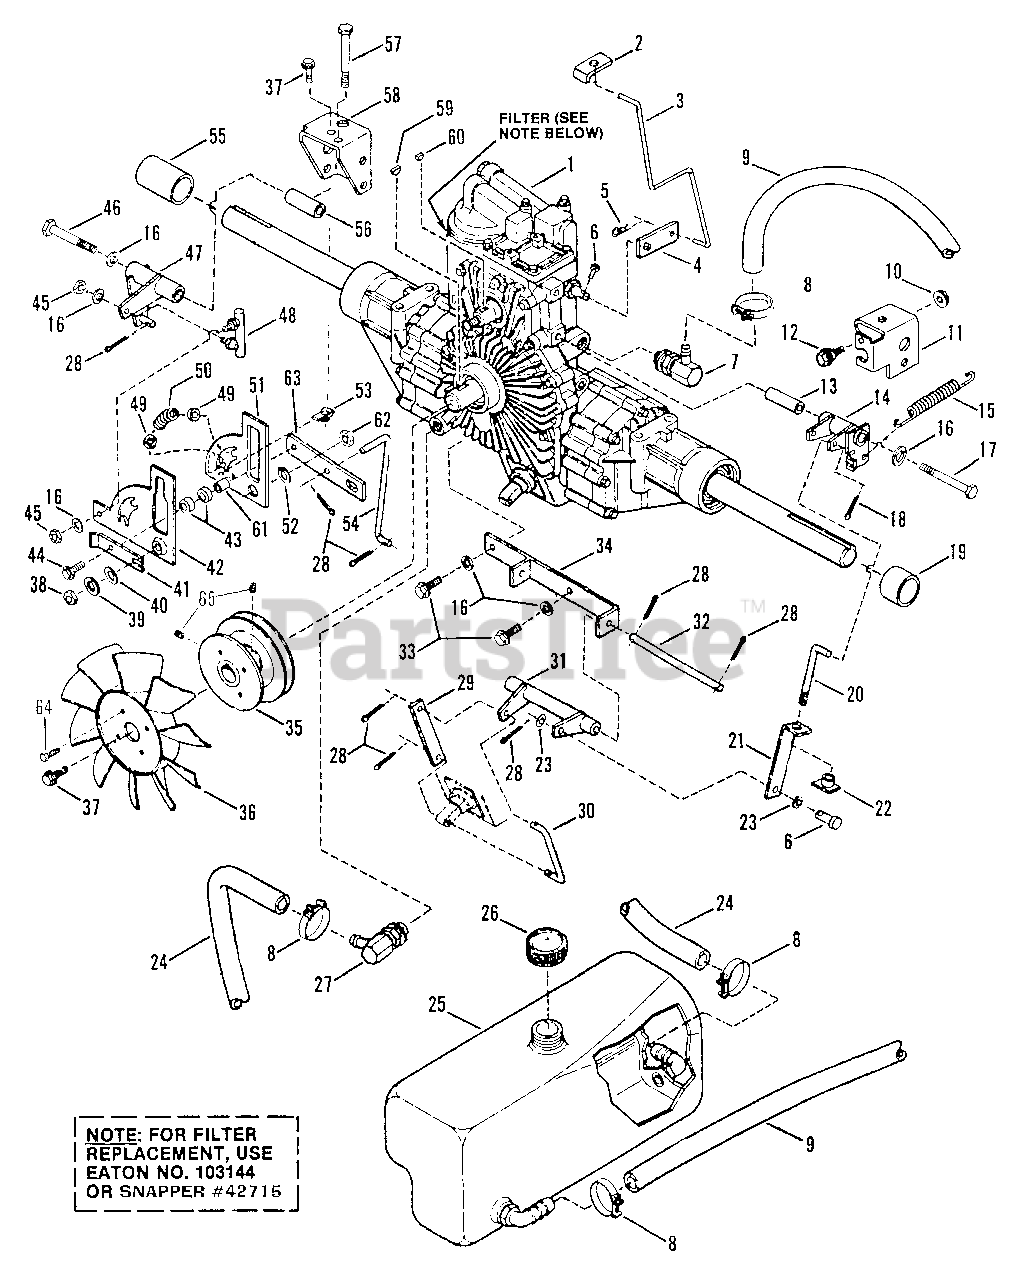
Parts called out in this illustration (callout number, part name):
1	TRANSMISSION, Hydro
2	LATCH, Roll Release
3	ROD, Roll Release
4	ARM, Roll Release
5	PIN, Hair
6	PIN, 1/4 x 5/8" Clevis
7	FITTING, 90°.
8	CLAMP, 3/16"
9	HOSE, Supply
10	NUT, 5/16-18 Hex Flange Lock
11	BRACKET, Neutral Return
12	SCREW, 5/16-18 x 3/4" Shoulder
13	SPACER, Short
14	PIVOT, Neutral Return
15	SPRING
16	WASHER, 5/16 Split Lock
17	BOLT, 5/16-18 x 2-1/2" hex Head Grade 2
18	PIN, 1/4 x 7/8" Self-Lock Cotter
19	SPACER, Wheel, L.H.
20	LINK, Parking Brake Adjusting
21	BRACKET, Parking Brake
22	TEENUT, 1/4-20
23	WASHER, 1/4 Flat
24	HOSE, Return
25	ASS'Y, Oil Tank
26	CAP, Oil Tank (Vented)
27	FITTING, Hose 70°.
28	PIN, 3/32 x 3/4" Cotter
29	RETAINER, Brake Link
30	LINK, Parking Brake
31	PIVOT, Parking Brake
32	PIN, Parking Brake Pivot
33	SCREW, 5/16-18 x 3/4" Hex Head Cap, Grade 2
34	BRACKET, Parking Brake Pivot
35	PULLEY, input
36	FAN
37	BOLT, 5/16-18 x 1/2" Hex Flange Lock, Gr. 5
38	NUT, 3/8-16 Hex
39	WASHER, 3/8 Split Lock
40	WASHER, 3/8" Flat
41	BRACKET, Retainer
42	CAM, Neutral Return
43	ROLLER
44	BOLT, 1/4-20 x 7/8" Hex Head, Gr.5
45	NUT, 5/16-24 Hex
46	SCREW, 5/16-18 x 3-3/4" Hex Head Cap
47	BELLCRANK, Speed Control
48	LINK, Shift
49	WASHER, Special
50	SPRING
51	GUIDE, Roller
52	RING, 1" Retaining
53	U-NUT, M6
54	LINK, Neutral Return
55	SPACER, Wheel, R.H.
56	SPACER, Long
57	BOLT, M6 Threads. x 4" Adjusting
58	BRKT, Neutral Adj.
59	KEY, #605 Woodruff
60	KEY, #404 Woodruff
62	NUT, 1/4-20 Hex Ctr. Lock, Gr. B or 5
63	ARM, Neutral Return
64	SCREW, 1/4-20 x 5/8" Self-Tap
65	SCREW, 5/16-18 x 5/8" Set
